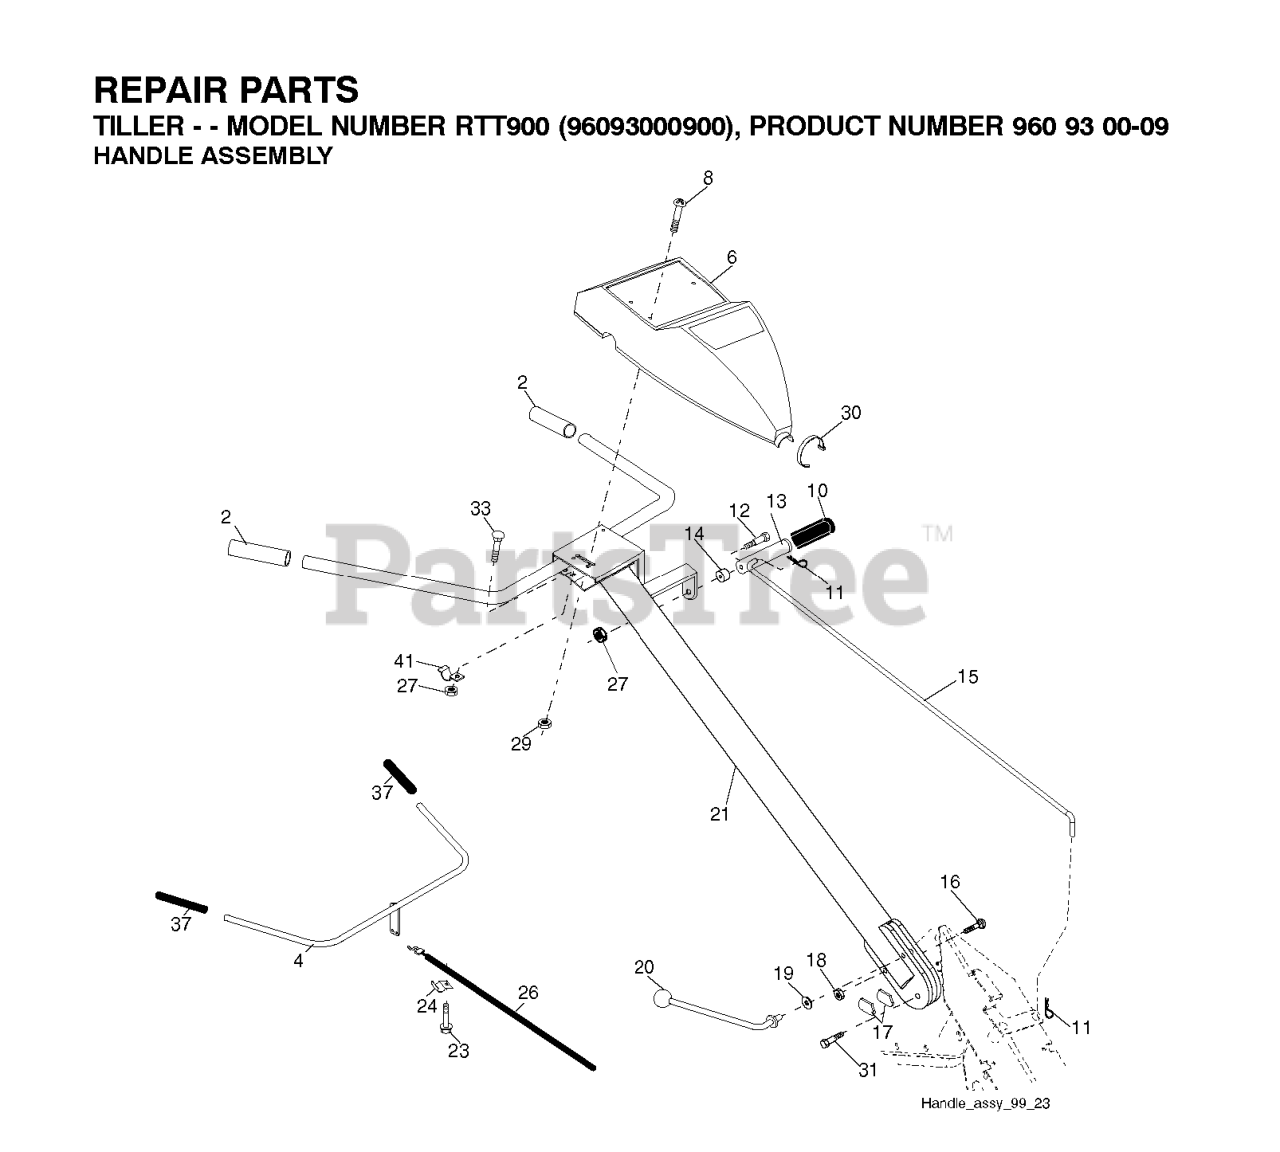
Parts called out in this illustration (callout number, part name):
2	GRIP.1X5.06
4	CONTROL BAR ASSY
6	RP PANEL, CONTROL
8	SCREW.PNHD.10-24
10	GRIP T
11	RETAINER M
12	SHOULDER BOLT ST
13	HANDLE.SHIFT.TILLER
14	GROMMET.RUBBER.CRT.TILLER
15	SHIFT ROD CRT
16	BOLT D
17	LOCK.HANDLE.CRT
19	WASHER CRT
20	LEVER.LOCK.CRT
21	REPL BY 532 1805-17
23	TAPPING SCREW
24	CONDUIT.CLIP.PLATED
26	CABLE.CLUTCH
27	NUT T
29	NUT **
30	TIE CABLE CRT
31	BOLT.PIVOT
37	GRIP BAR CRT(1)
41	CLAMP.BAR.CRT.BLACK
